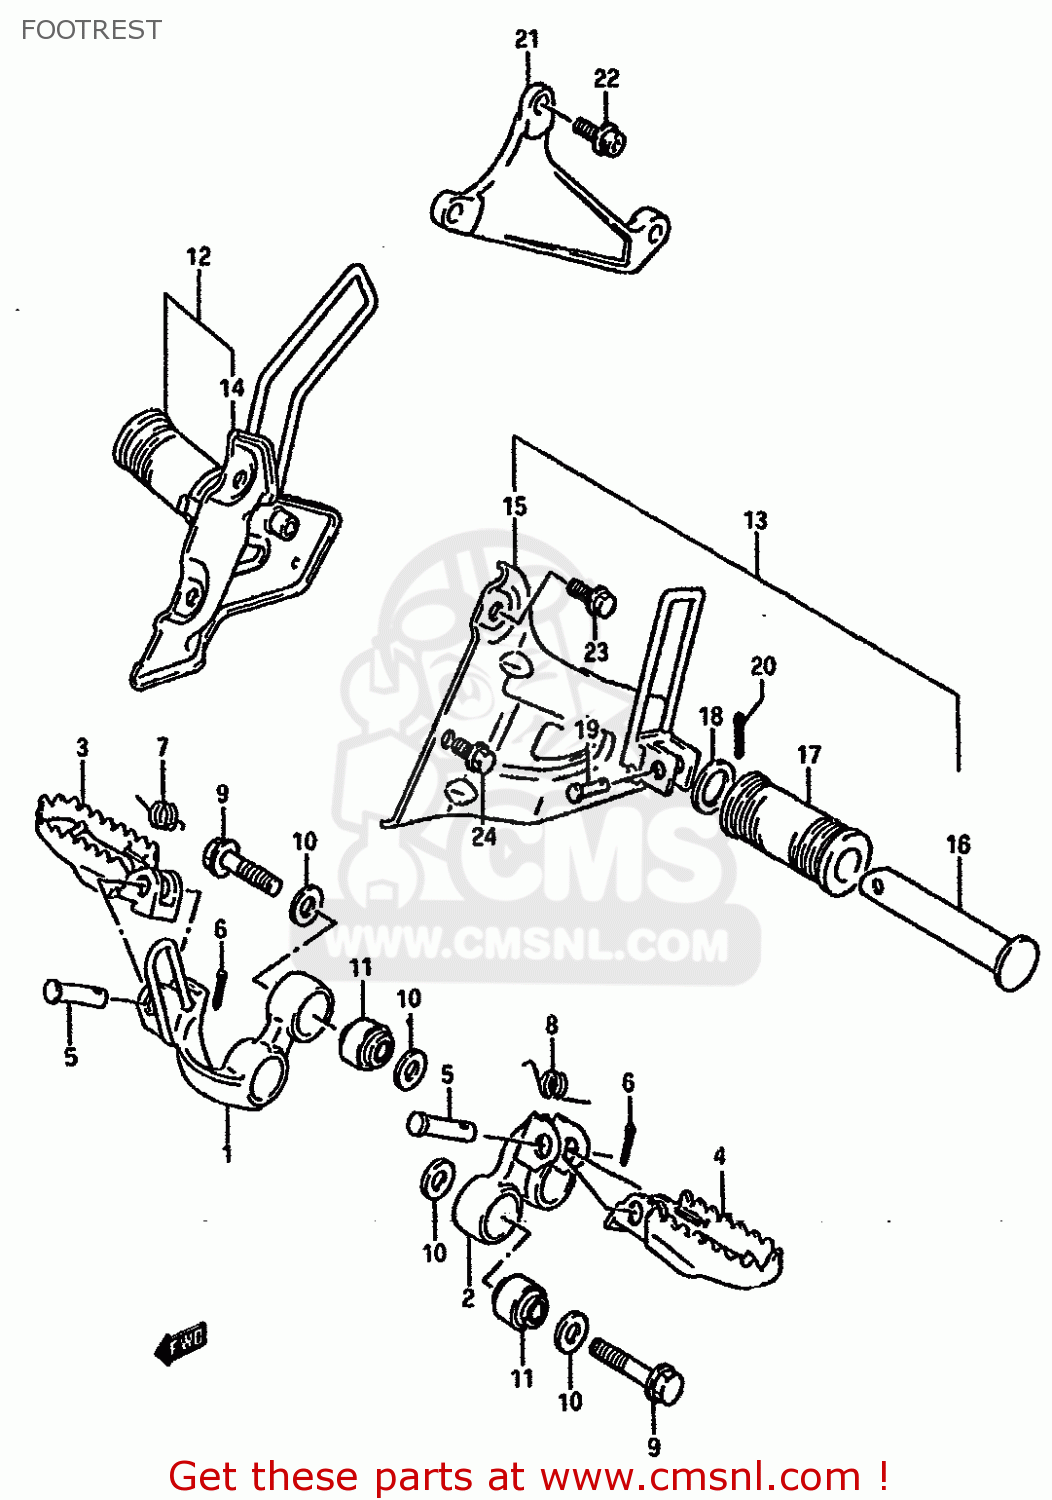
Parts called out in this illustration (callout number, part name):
1	BAR,FOOTREST RH (BLUE)
2	BAR,FOOTREST LH (BLUE)
3	FOOTREST,FR,R
4	FOOTREST,FRONT LH (BLUE)
5	PIN
6	PIN 20X20
7	SPRING
8	SPRING
9	BOLT
10	WASHER(10.1X23X2.3)
11	BUSHING 10X28.1X19
12	FOOTREST,PILLION RH (BLUE)
13	FOOTREST,PILLION LH (BLUE)
14	HOLDER,RH (BLUE)
15	HOLDER,RH (BLUE)
16	BAR,FOOTREST RUBBER
17	RUBBER,PILLION FOOTREST
18	WASHER (19.5X32X2)
19	PIN
20	PIN
21	BRACKET,MUFFLER
22	BOLT
23	BOLT
24	BOLT
